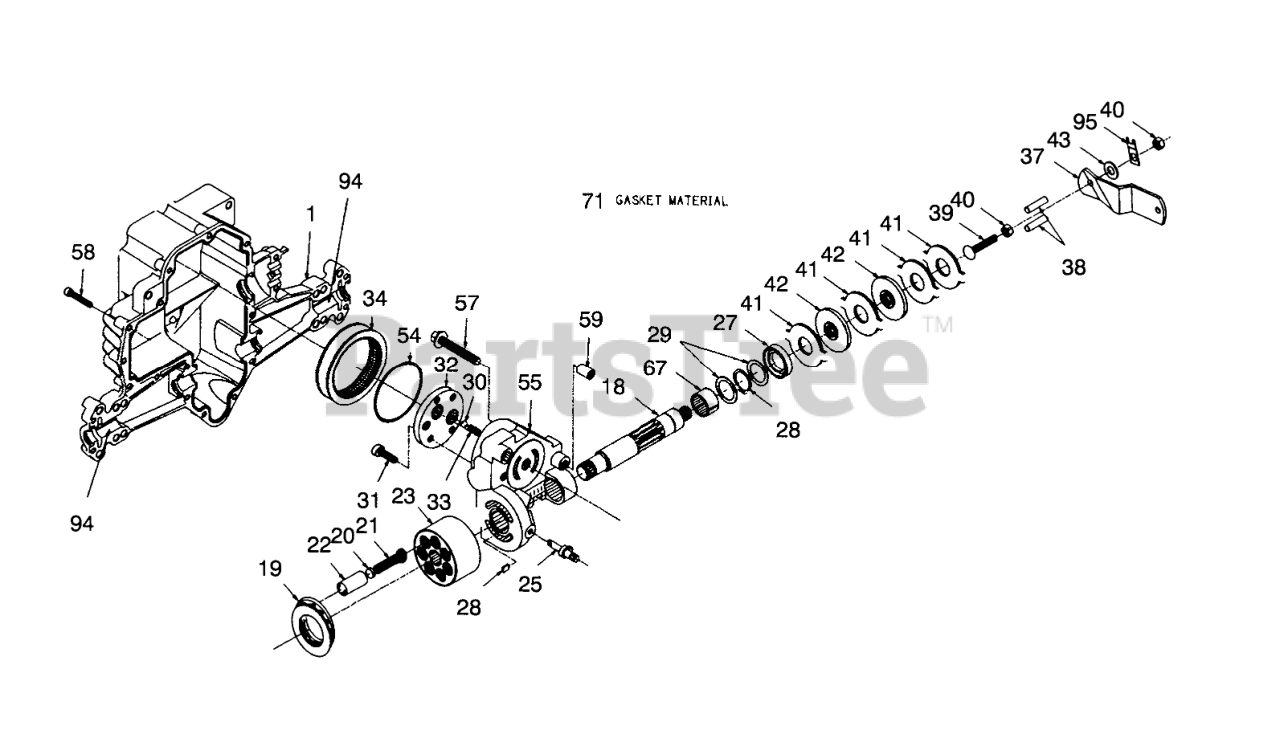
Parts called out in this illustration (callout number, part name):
1	Housing-Lower
18	Shaft-Motor
20	Seat-Piston Spring
21	Spring-Piston
23	Block-Cylinder (Motor)
25	Actuator-Bypass
26	Plate-Bypass
27	Seal-Lip
29	Washer
30	Ball
31	Spring-Check Valve
32	Plate-Check Valve
33	Socket Hd. Cap Screw
34	Oil Filter Element
37	Lever-Brake
38	PIN - ACTUATING
39	Bolt
40	NUT-LOCK, NI
41	Stator-Brake
42	Rotor-Brake
43	WASHER-PIVOT
54	O Ring
55	Center-Section
57	Bolt
58	Bolt
67	Du Bearing
71	Gasket Material
94	Grease Durina "O"
95	STRAP - LOCKING
